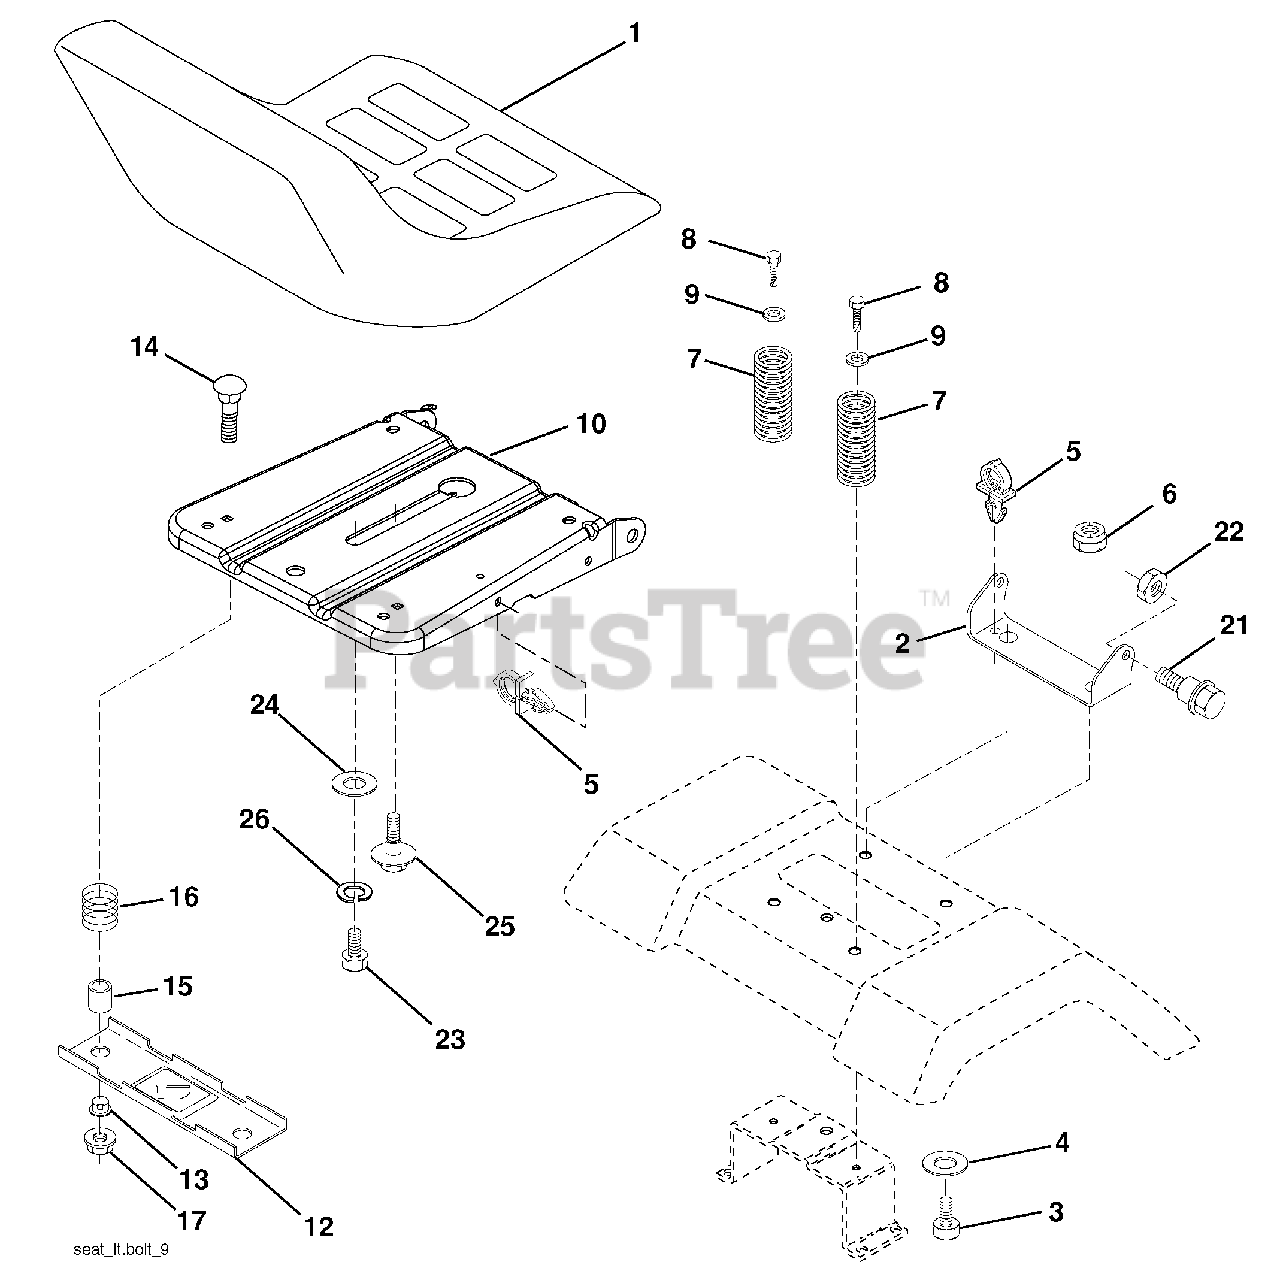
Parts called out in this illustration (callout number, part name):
1	Seat
2	Bracket Seat Pivot
3	Bolt Hex 3/8 - 16 x 1
4	Washer 13/32 x 1 x10 Ga.
5	Clip Push-In Hinged
6	Nut Lock Hex w/Ins 3/8 - 16
7	Spring Seat Cprsn 2 250 Blk Zi
8	Screw 3/8-16 x 1.5
9	Washer 13/32 x 1 x 14 Ga.
10	Pan Asm. Seat
12	Bracket Pnt Mounting Switch
13	Bushing Snap Blk Nyl
14	Bolt Rdhd Sht Nk 1/4 - 20 x 1 -1/2
15	Spacer Split .28 x .96
16	Spring Cprsn
17	Nut Lock 1/4 Lge Flg
21	Bolt Shoul der 5/16-18 unc-2A
22	Nut Lock Hex w/Ins 5/16 - 18
23	Bolt Hex
24	Washer 17/32 x 1-3/16 x 12 Ga.
25	Bolt Shoul der 5/16-18 x .62
26	Washer Lock Hvy Hlcl Spr 1/2
